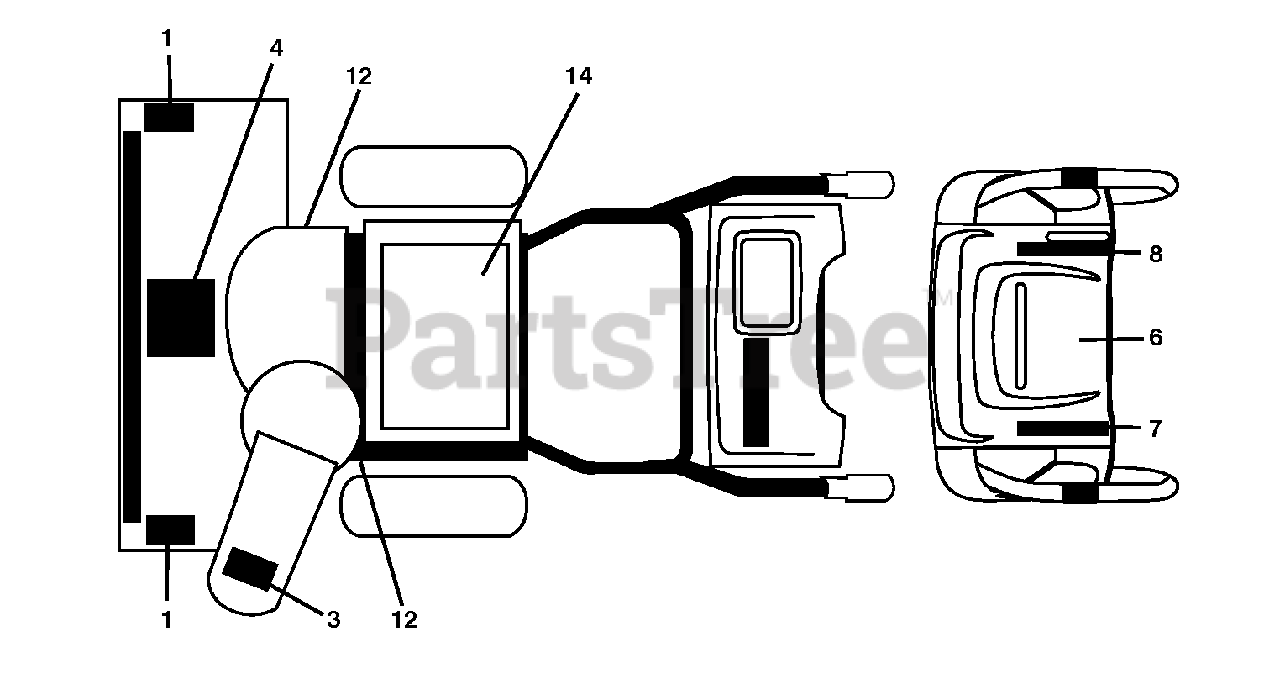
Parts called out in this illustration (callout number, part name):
1	DECAL.AUGER.SAFETY.
3	DECAL.CHUTE.SAFETY.
4	DECAL.AUGER."
6	DECAL.CONSOLE.INSTRUCTION
7	DECAL.CONS.LT.WO/DEFL
8	DECAL.CONS.RT.SPD/LEV/PWRST
12	DECAL.BELT.GUARD.
14	DECAL.FENDER
